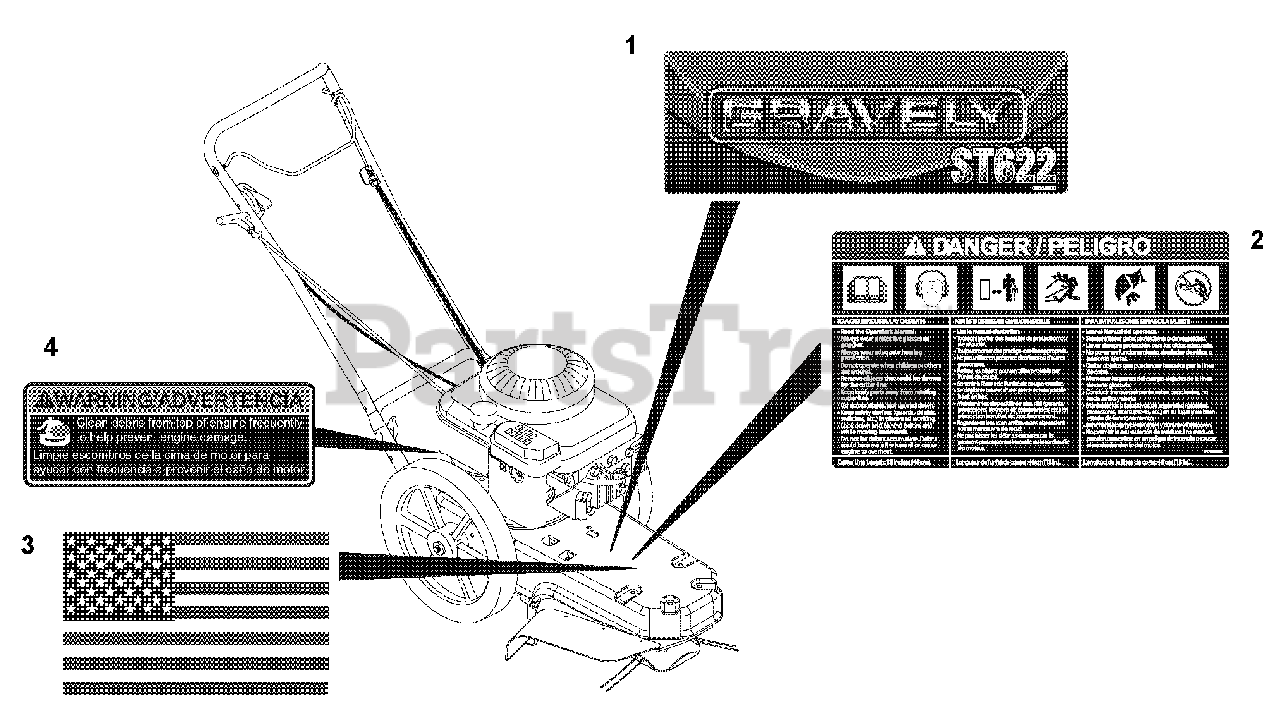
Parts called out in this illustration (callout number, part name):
1	Decal-Gravely ST 622
2	Decal-Danger
3	Decal - Flag
4	Decal, Trimmer Debris
